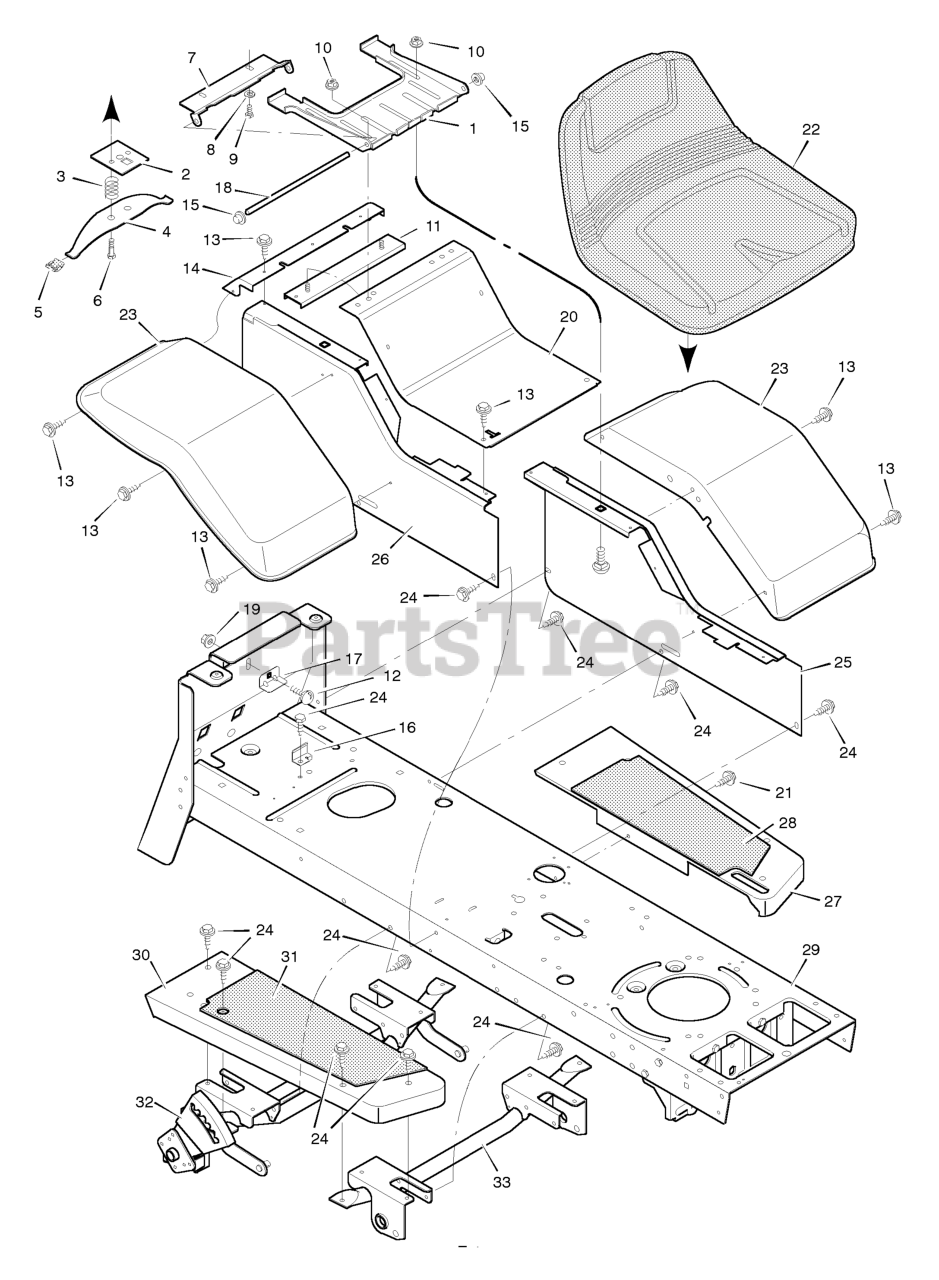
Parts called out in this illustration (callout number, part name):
1	Bracket, Seat
2	Plate Assembly, Switch
3	Spring, Compression
4	Spring, Seat
5	Glide, Spring
6	Bolt, Shoulder
7	Support, Seat
8	Lockwasher
9	Bolt, Hex
10	Locknut, Flange
11	Channel Assembly
12	Bolt, Carriage
14	Insert, Rear
15	Push On Cap
16	Support, Battery
17	Clamp, Battery
18	Rod, Pivot
19	Locknut
20	Panel, Top
21	Fastener, Panel
25	Panel, Left
26	Panel, Right
27	Running Board, Left
28	Mat, Left
29	Frame Channel
30	Running Board, Right
31	Mat, Right
32	Lifter and Support Assembly
33	Support Assembly, Front
